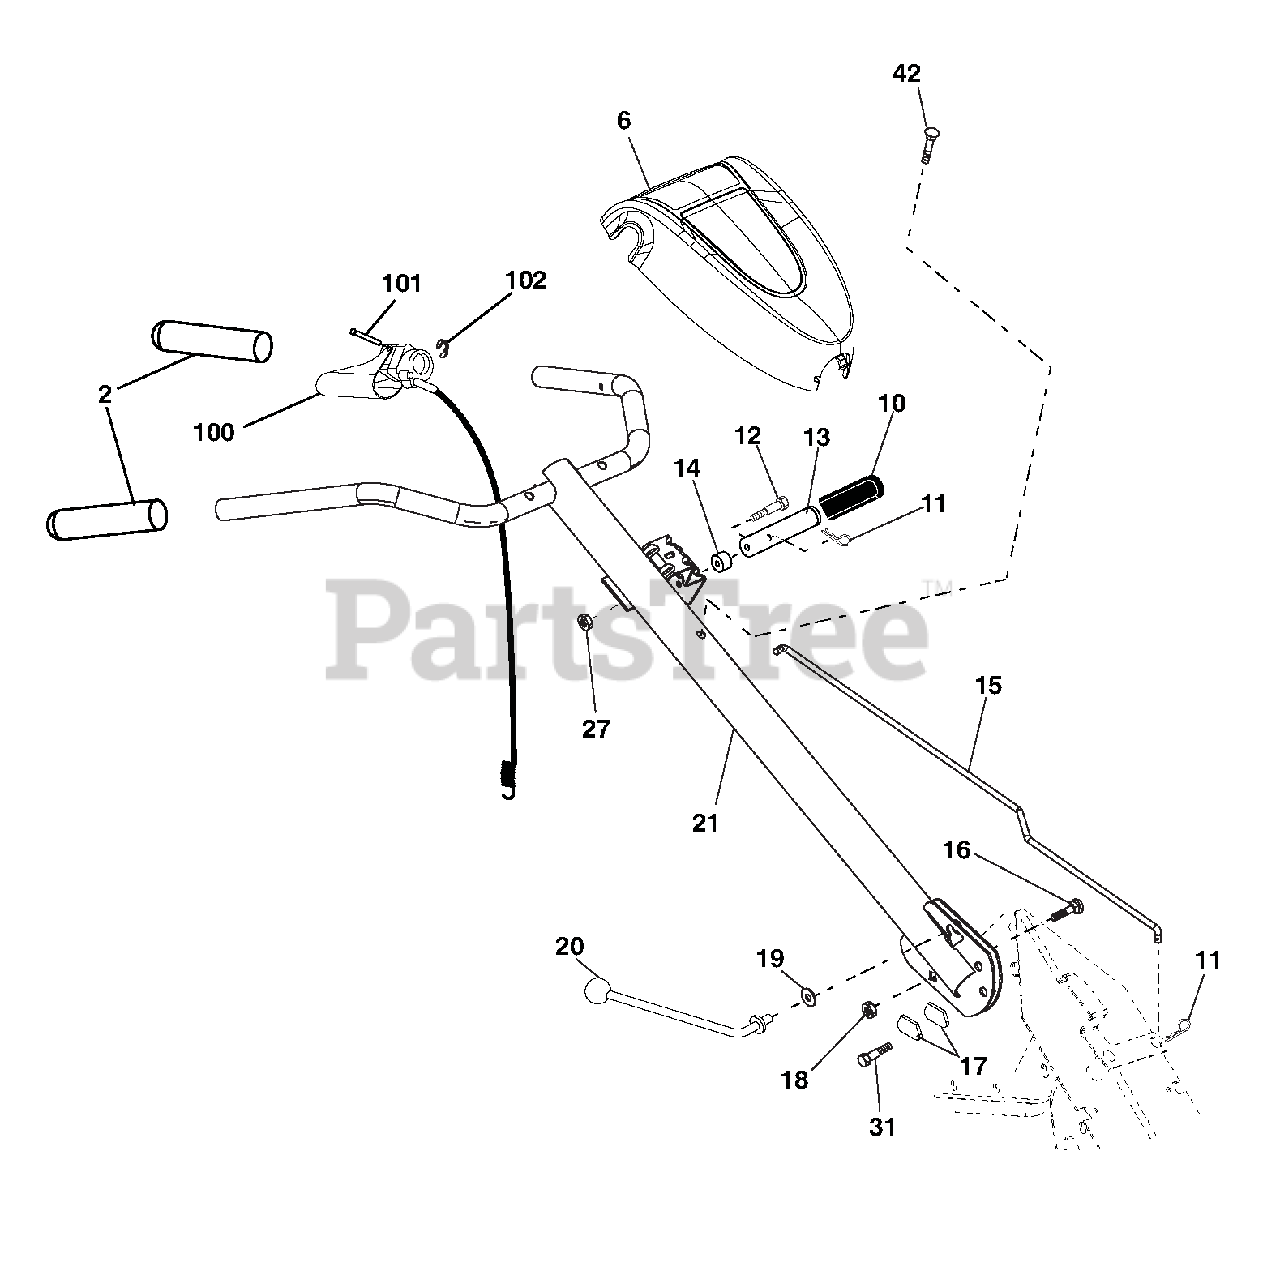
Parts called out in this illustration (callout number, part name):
2	Grip, Handle
6	Console Control
10	Handle, Grip
11	Retainer Spring
12	Bolt, Shoulder
13	Handle, Shift
14	Grommet, Rubber
15	Rod, Shift
16	Bolt 3/8-16 x 1 Gr. 5
17	Lock, Handle
18	Nut, Hex, Crownlock 3/8-16
19	Washer 13/32 x 1 x 11 Ga.
20	Lever, Lock, Handle
21	Handle, Assemble
27	Nut, Hex Flange 1/4-20 unc
31	Bolt, Pivot
101	Pin, Pivot
102	Retaining Ring
